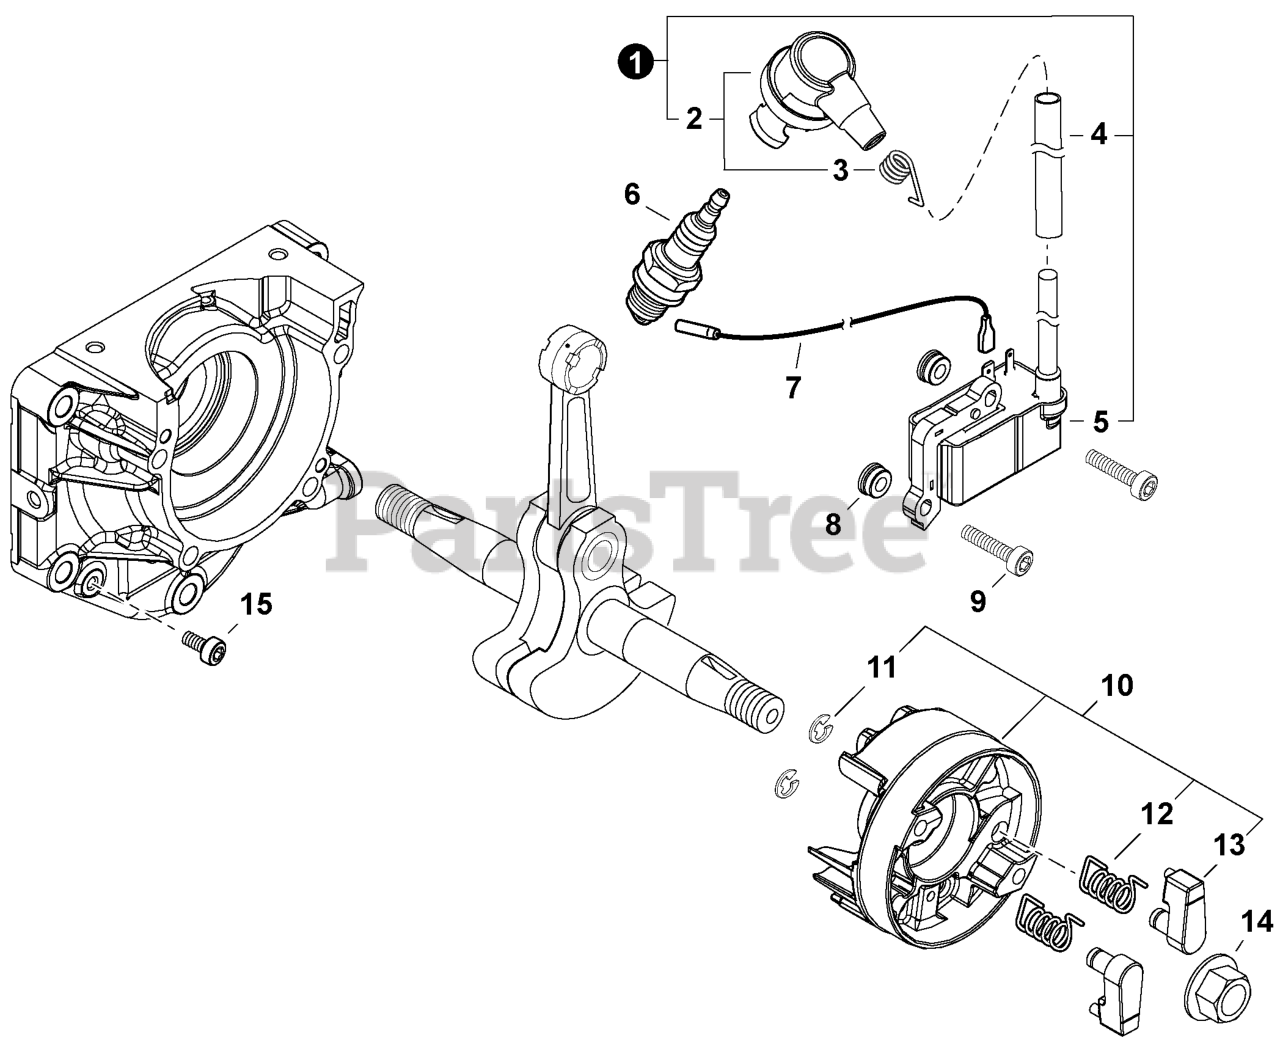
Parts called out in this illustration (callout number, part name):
1	COIL ASSY, IGNITION
2	CAP ASSY, SPARK PLUG
3	TERMINAL, SPARK PLUG
4	TUBE, INSULATOR
5	COIL, IGNITION
6	SPARK PLUG - CMR7H
7	LEAD - IGNITION
8	COLLAR 4
9	BOLT 4x20
10	FLYWHEEL
12	SPRING, RETURN
13	PAWL, STARTER
14	NUT, FLANGE 10x1.25
15	BOLT, TORX 4x10
